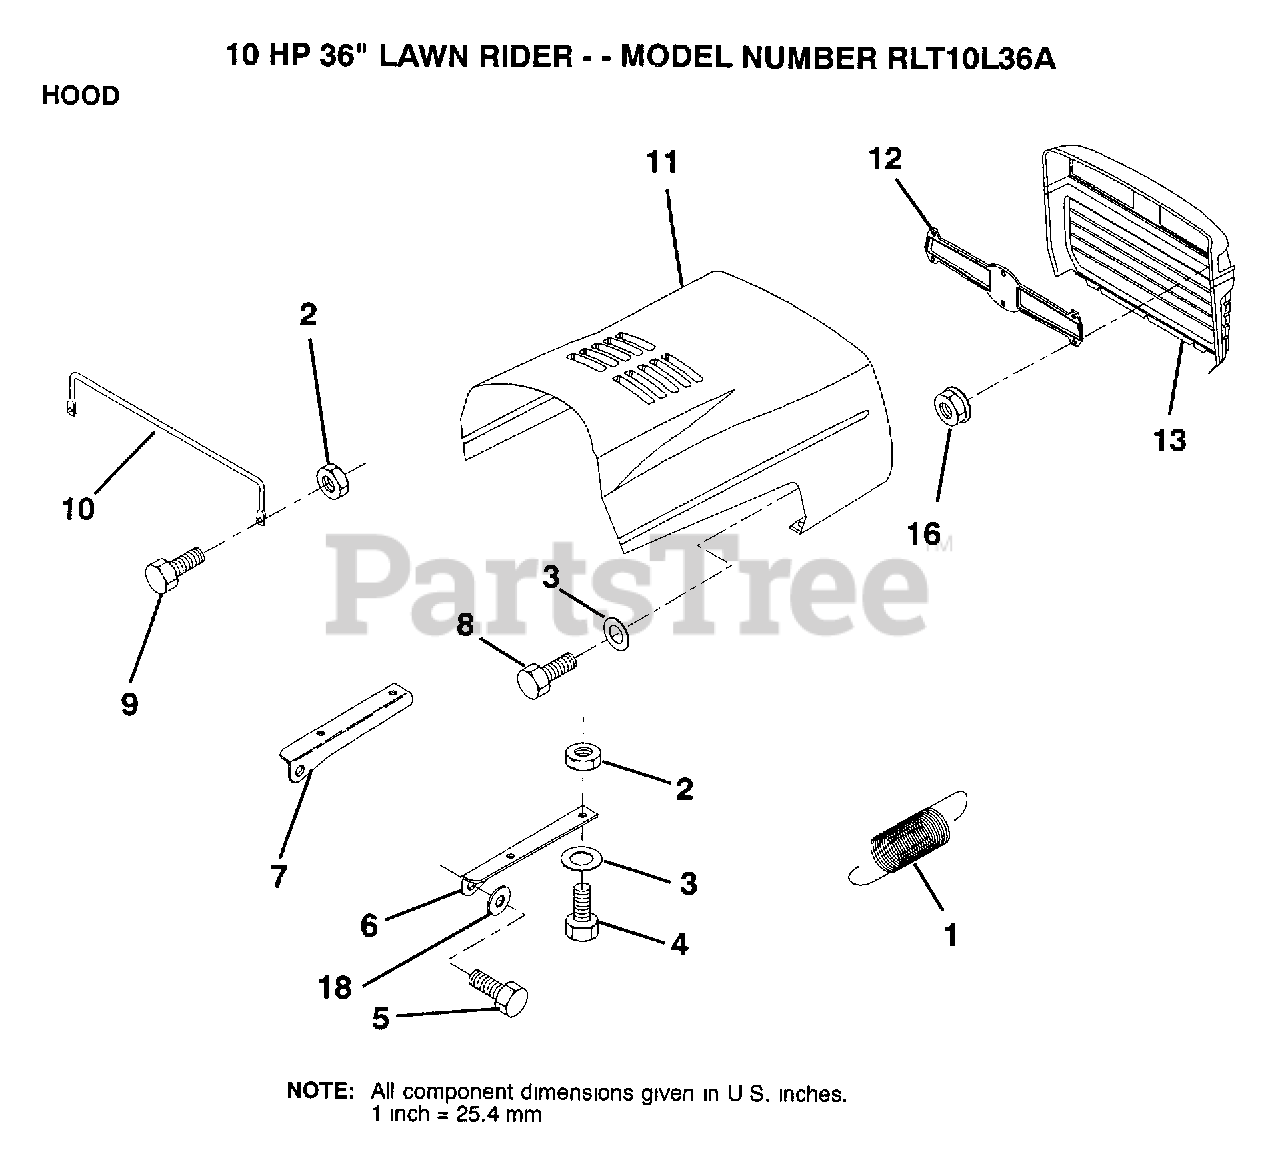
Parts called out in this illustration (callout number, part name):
1	EXT SPRING
2	NUT
3	WASHER
4	BOLT
6	BRKT HOOD RH
7	BRKT HOOD LH
10	"BRACE,HOOD"
11	HOOD
16	NUT
18	WASHER
